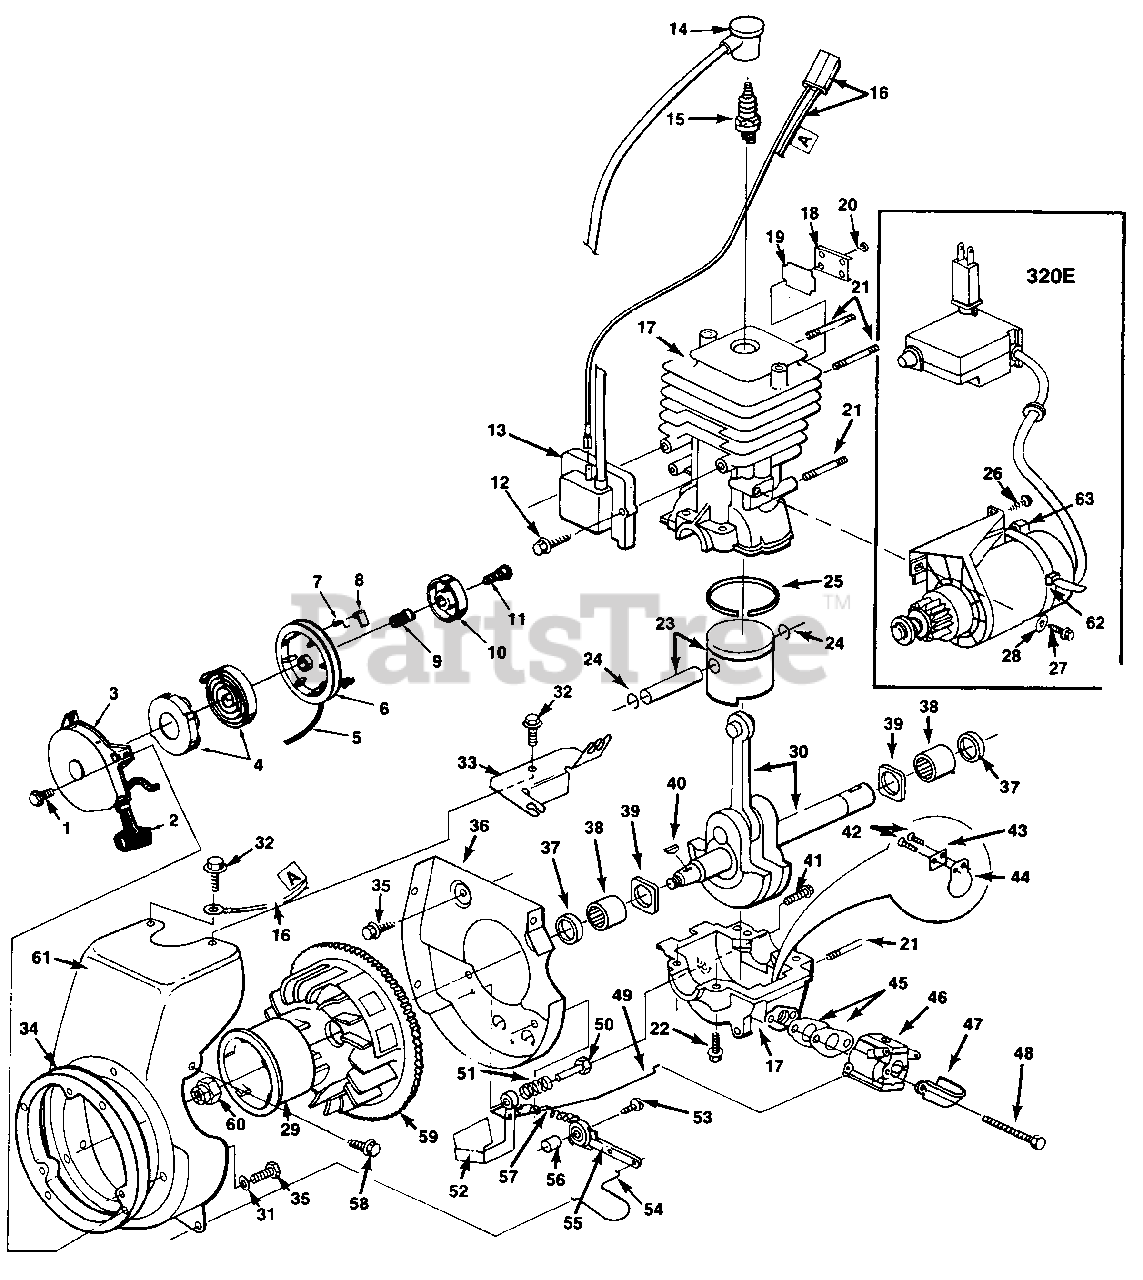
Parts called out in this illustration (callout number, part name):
2	HANDLE ASSEMBLY
3	HOUSING ASSEMBLY
4	SPRING & KEEPER ASSEMBLY
5	ROPE- 75"
7	SPRING-Dog
9	SPRING-Brake
12	SCREW-Thd. rolling
13	MODULE-Ignition
14	COVER-Spark
15	SPARK PLUG (CJ8Y)
16	LEAD-Electrical
17	CYLINDER & CRANKCASE
18	COVER-Cylinder
20	SCREW-Thd. rolling
21	STUD-Thd. rolling
22	SCREW-Sems hex hd
23	PISTON & PIN ASSEMBLY
24	RING-Pin retaining
25	PISTON RING
26	SCREW- 10-24 x 3/4
29	HUB- Starter
30	CRANKSHAFT ASSEMBLY
31	WASHER-Flat
32	SCREW-Thd. forming
33	BRACKET
35	SCREW-Thd. forming
36	PLATE-Fan housing
37	SEAL-Shaft
38	BEARING-Needle
39	WASHER-Thrust
40	KEY-Woodruff
41	SCREW
43	STOP-Reed
44	REED VALVE
45	SPACER-Carburetor
46	CARBURETOR Walbro (HDC-74)
47	SHIELD-Carburetor
48	SCREW-Thd. forming
49	THROTTLE ROD
50	PIN-Pivot
52	VANE-Governor
53	SCREW-Tap pan head
54	SPRING-Torsion
55	LEVER-Throttle
56	SPACER-Gov. vane
57	SPRING-Extension
58	SCREW-Tap hex hd.
60	NUT- 7/16-20 hex
61	HOUSING-Fan
62	STRAP-Tie
